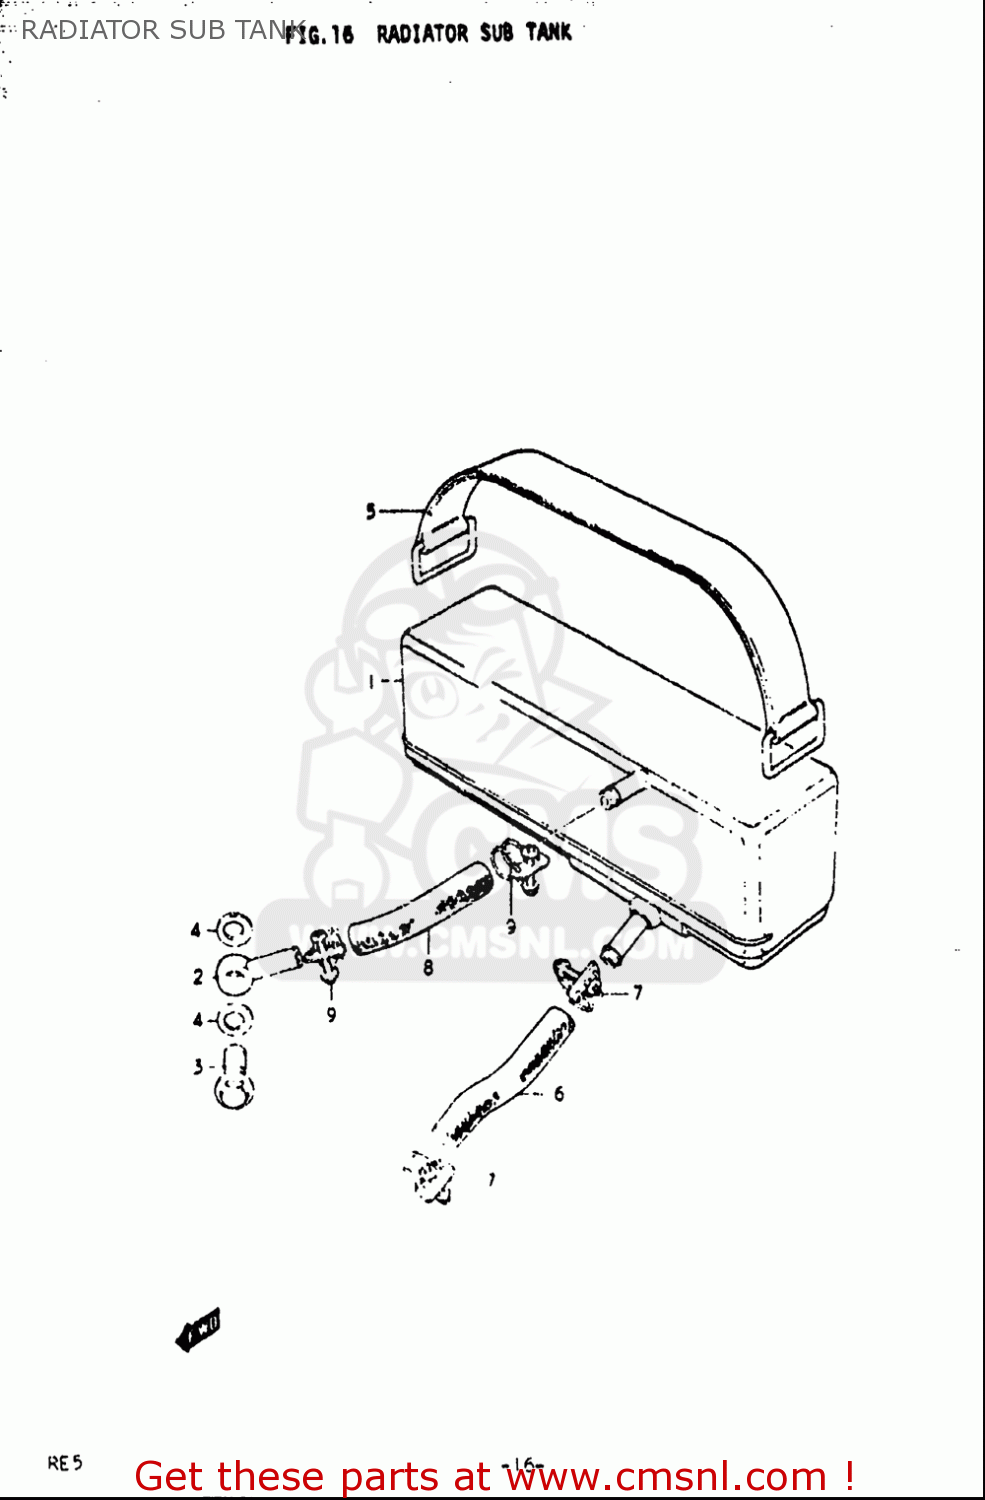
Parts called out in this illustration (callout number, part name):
2	UNION
3	UNION BOLT
4	GASKET(6.2X11X1).2 (NAS)
5	BAND
6	HOSE(5.5X9.5X400)
7	CLAMP
8	HOSE(5.5X9.5X52)
9	CLAMP
